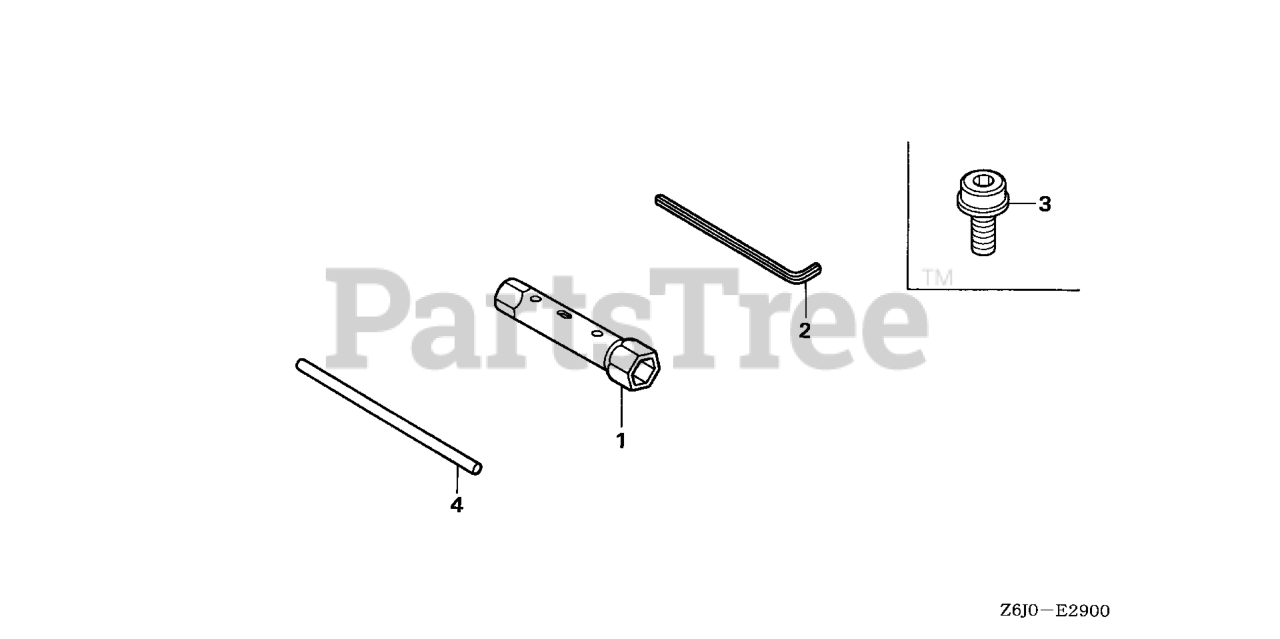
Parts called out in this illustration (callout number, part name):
1	WRENCH, PLUG (16X19)
2	WRENCH, HEX. (4MM)
4	BAR A, HANDLE
